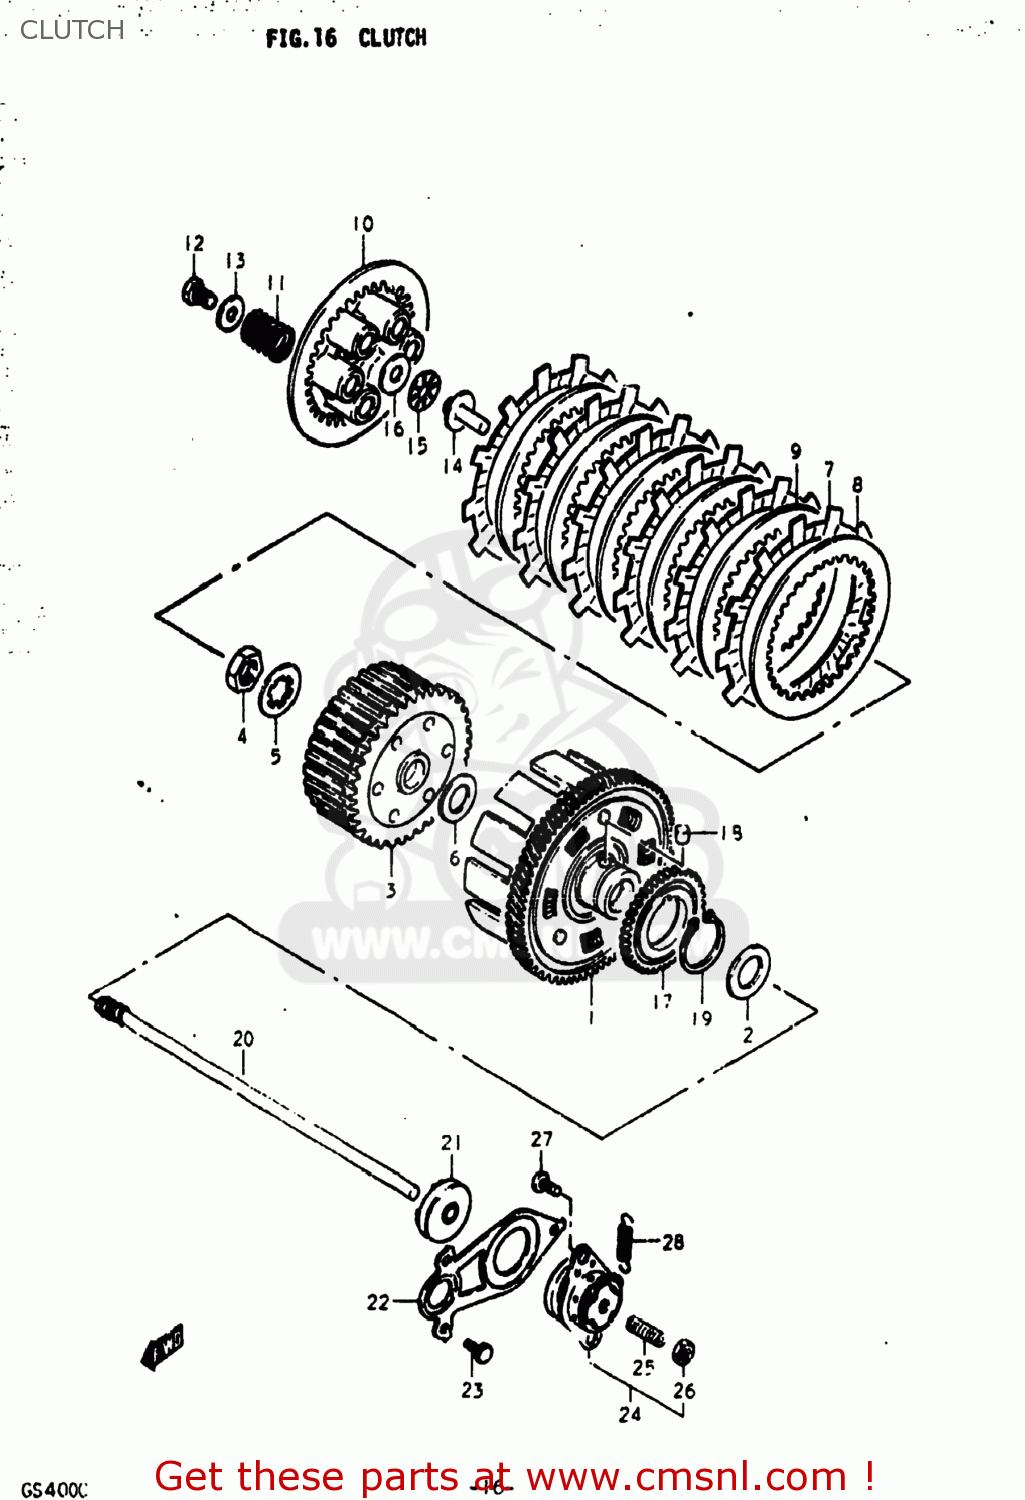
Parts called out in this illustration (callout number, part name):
1	GEAR ASSEMBLY,PRIMARY DRIVE
2	WASHER
3	HUB,CLUTCH SLEEVE
4	NUT (20MM)
5	WASHER,LOCK
6	WASHER(20X38X2)
7	PLATE,CLUTCH DRIVE (NAS)
8	PLATE,CLUTCH DRIVEN(T:2.0) (NAS)
9	PLATE,CLUTCH DRIVEN (NAS)
10	DISC,CLUTCH PRESSURE
11	SPRING
12	BOLT, UPPER
13	WASHER
14	PIECE,CLUTCH PUSH
15	BEARING(15X28X2)
16	WASHER
17	GEAR,OIL PUMP DRIVE
18	PIN(6X6)
19	CIRCLIP
20	ROD,CLUTCH PUSH
21	OIL SEAL
22	RETAINER,CL PUSH ROD OIL SEAL
23	BOLT
24	SCREW ASSEMBLY,CLUTCH RELEASE
25	SCREW
26	NUT 6MM
27	SCREW 6X12
28	SPRING
